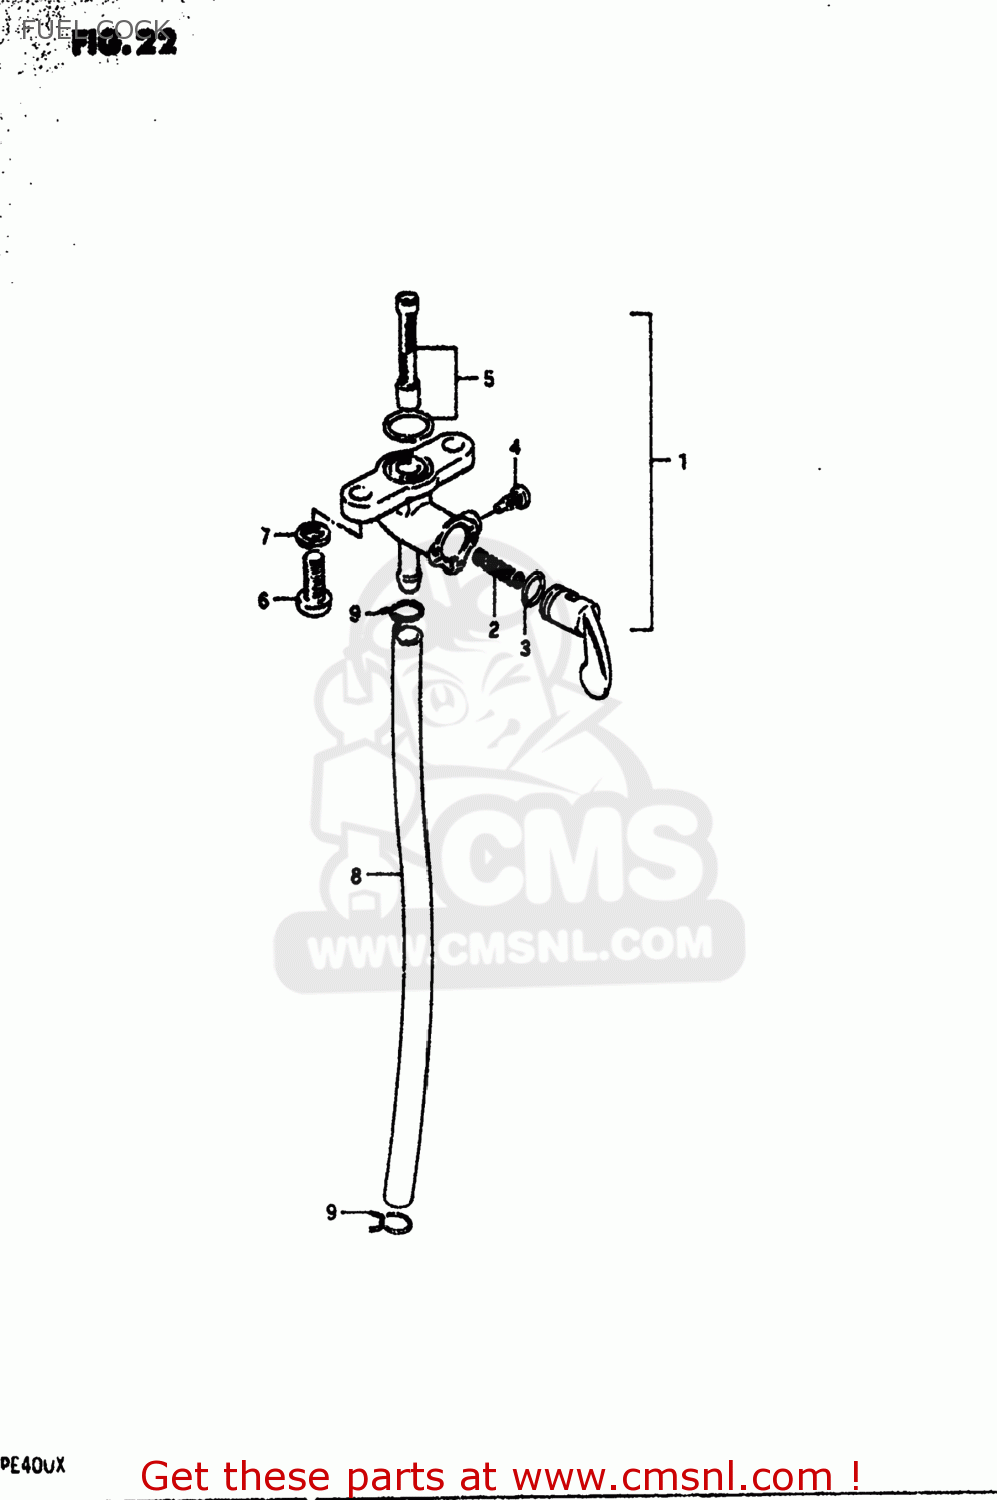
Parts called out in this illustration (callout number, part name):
1	COCK ASSEMBLY,FUEL
2	SPRING,FUEL COCK VALUE
3	O RING,LEVER
4	SCREW
5	FILTER SET FUEL
6	SCREW
7	LOCK WASHER
8	HOSE
9	CLAMP
